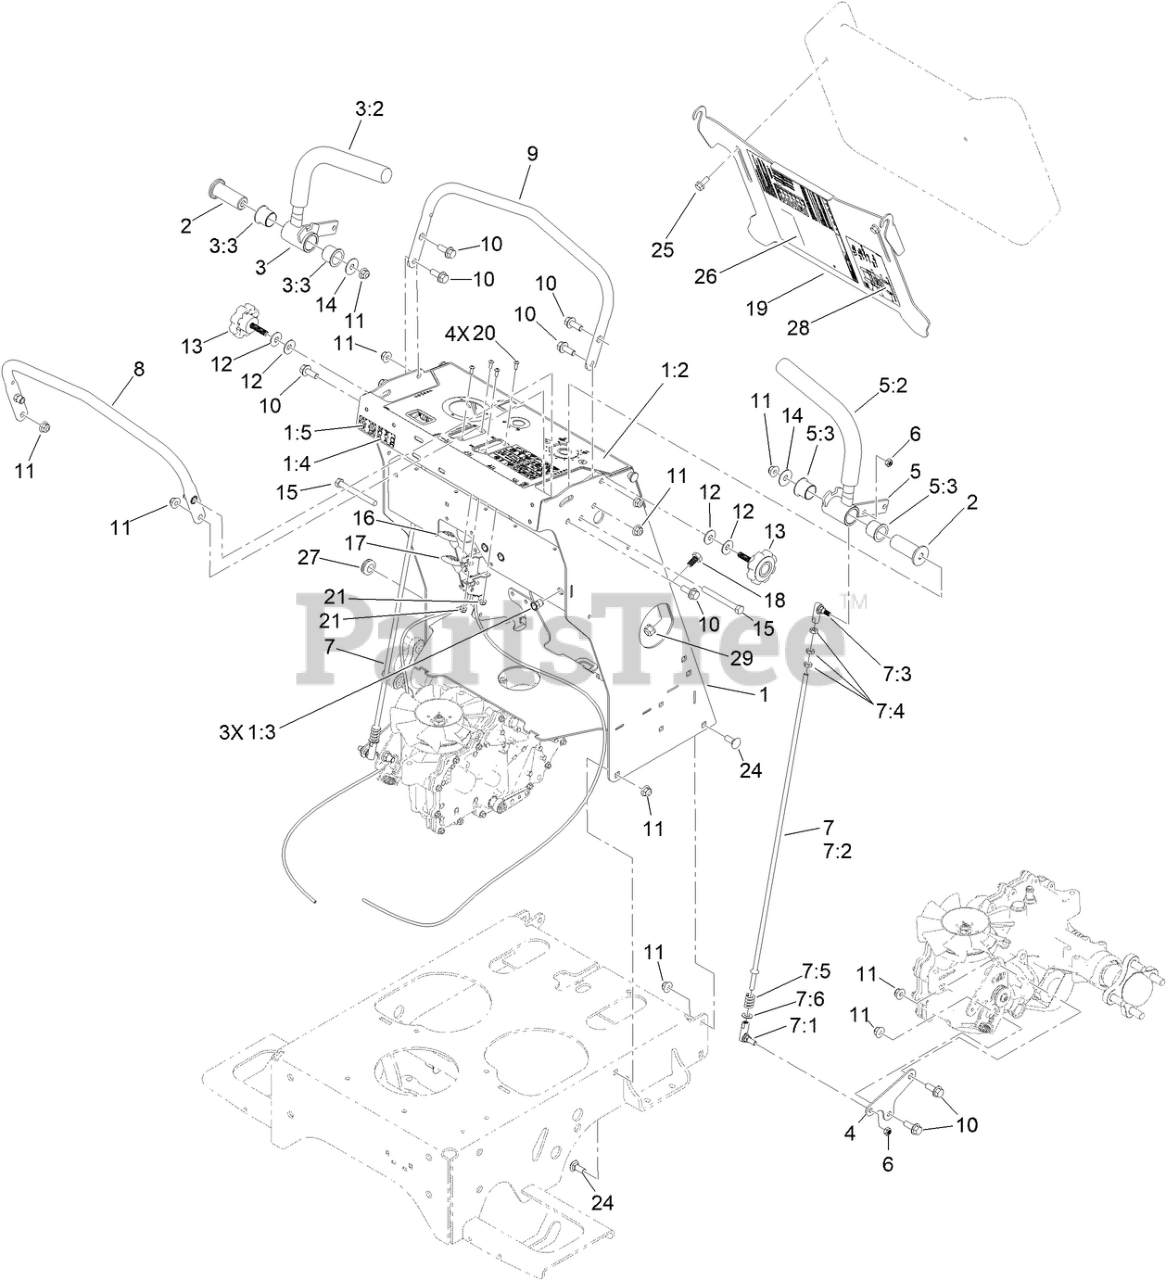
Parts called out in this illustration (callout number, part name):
1	TOWER-ASM W/DECAL
1:2	DECAL-CONTROL PANEL
1:3	NUT-CLINCH,HEX
1:4	DECAL-FUSE,MAIN
1:5	DECAL-FUSE,SOLID STATE
2	PIVOT-CONTROL, HANDLE
3	HANDLE-CONTROL, RH ASM
3:2	GRIP-CONTROL, MOTION
3:3	BUSHING-PIVOT
4	ARM-CONTROL, RTN
5	HANDLE-CONTROL, LH ASM
5:2	GRIP-CONTROL, MOTION
5:3	BUSHING-PIVOT
6	NUT-LOCK, NI
7	LINKAGE-MOTION CONTROL ASM
7:1	Balljoint-SS
7:2	ROD-CONTROL, MOTION
7:3	3/8-24 SS BALL JOINT\N367
7:4	Nut-Hex
7:5	SPRING-COMPRESSION
8	BAR-SPEED, ASM
9	BAR-REFERENCE
10	SCREW-HHF
11	Nut-Hex Flange
12	WASHER-SPRING
13	KNOB-FLUTED
14	WASHER-FLAT
15	HHCS,3/8-16X3-1/2,ST/ST 18-8
16	CONTROL-THROTTLE
17	CONTROL,CHOKE
18	MAGNET-STUD, THREADED
19	PLATE-KNEE PAD
20	Screw-HSBH
21	Nut-Hex Flange
24	SCREW-CARR
25	SCREW-HHF
26	DECAL-SPRAY CHART
27	GROMMET
28	DECAL-SERVICE AID
29	NUT-LOCK, NI
